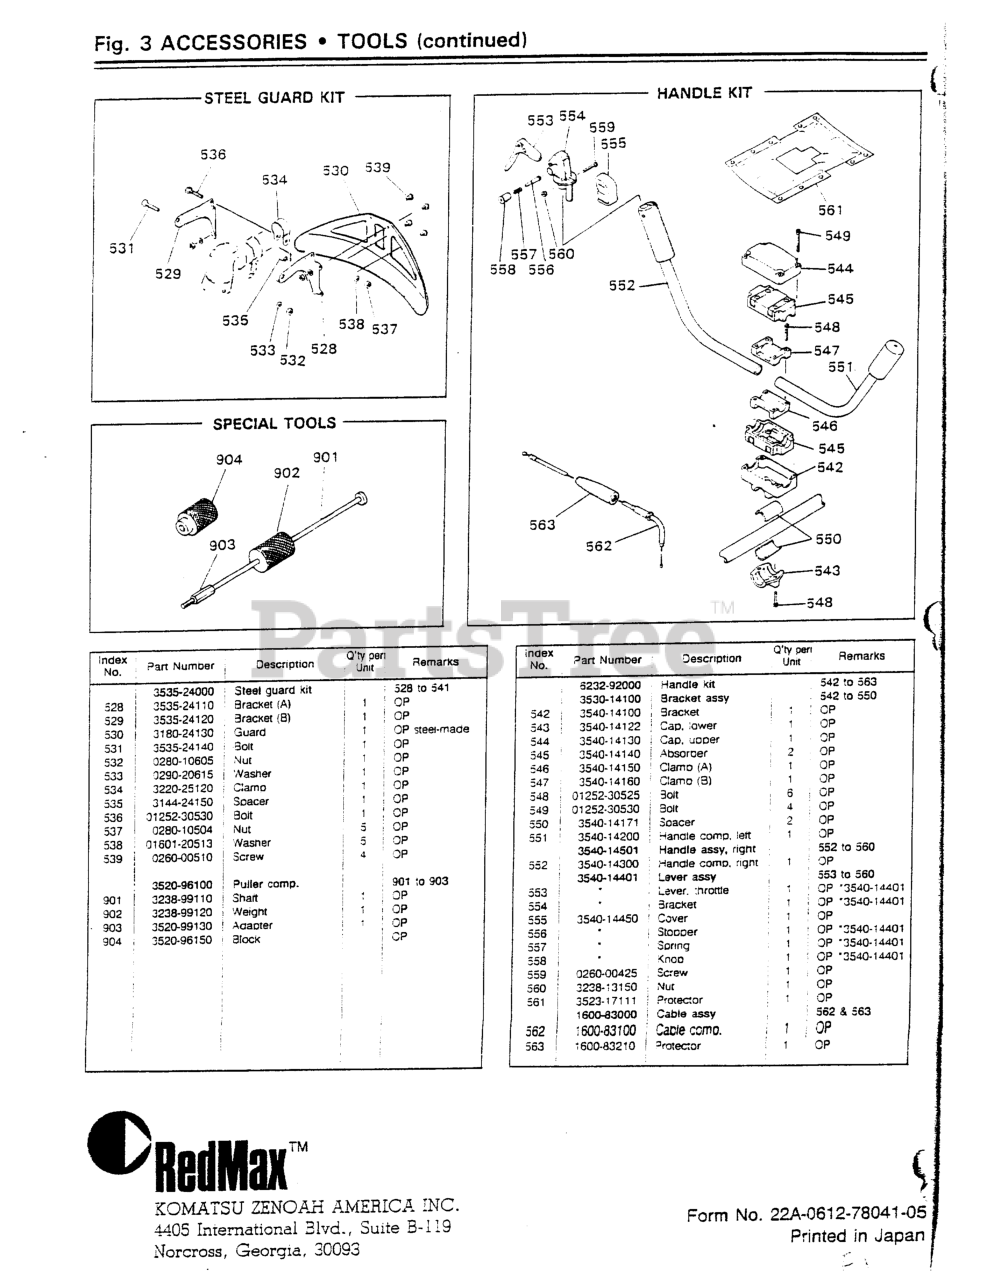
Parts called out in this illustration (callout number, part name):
528	BRACKET (A)
530	GUARD (NLA)
532	NUT, M6 X 5
533	WASHER, M6 X 15
536	BOLT, M5 X 30
537	NUT, M5 X 4
538	WASHER, SPRING M4 x 1.3
543	CAP, LOWER
544	CAP, UPPER
545	ABSORBER
546	CLAMP (A)
547	CLAMP (B)
548	BOLT, M5 X 25
549	BOLT, M5 X 30
551	HANDLE COMPL, LEFT
552	HANDLE (R) CO
559	SCREW, M4 X 25
563	PROTECTOR
901	SHAFT (TOOL)
903	ADAPTER (B) (TOOL)
904	BLOCK (TOOL)
